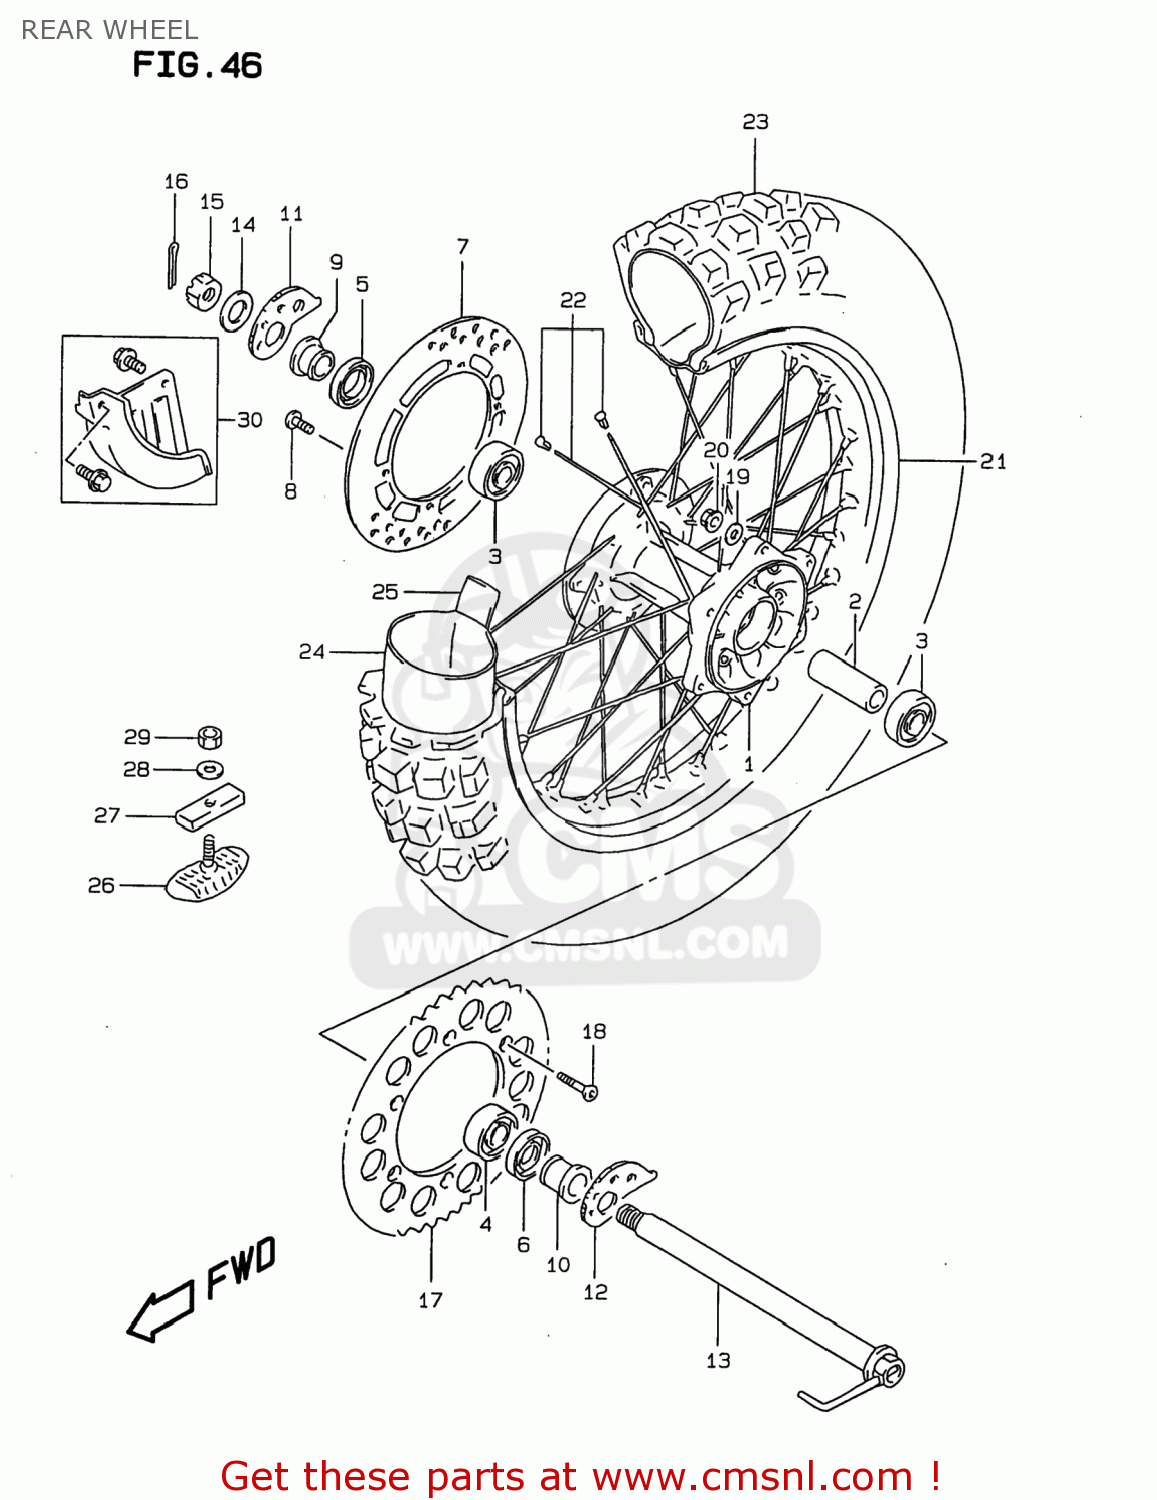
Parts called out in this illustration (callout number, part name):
1	HUB,RR WHEEL
2	SPACER,RR HUB BEARING
3	BALL BEARING
4	BEARING
5	SEAL,OIL(26X42X8)
6	SEAL,OIL(26X47X5)
7	DISC,RR BRAKE
8	BOLT,BRAKE DISC
9	SPACER,RR AXLE,R
10	SPACER,RR AXLE,L
11	ADJUSTER,CHAIN,R
12	ADJUSTER,CHAIN,L
13	AXLE,RR
14	WASHER(19X32X3.2)
15	NUT
16	PIN,COTTER
17	SPROCKET,RR(NT:43)
18	SCREW(8X33.5)
19	WASHER
20	NUT
21	RIM,RR WHEEL(18X2.15 AL)
22	SPOKE SET,RR WHEEL
23	TIRE COMP,REAR 110/100-1
24	TUBE,INNER
25	PROTECTOR,INNER TUBE
26	STOPPER,BEAD(2.15)
27	CUSHION,BEAD STOPPER
28	WASHER
29	NUT
30	COVER SET,RR BRAKE DISC
